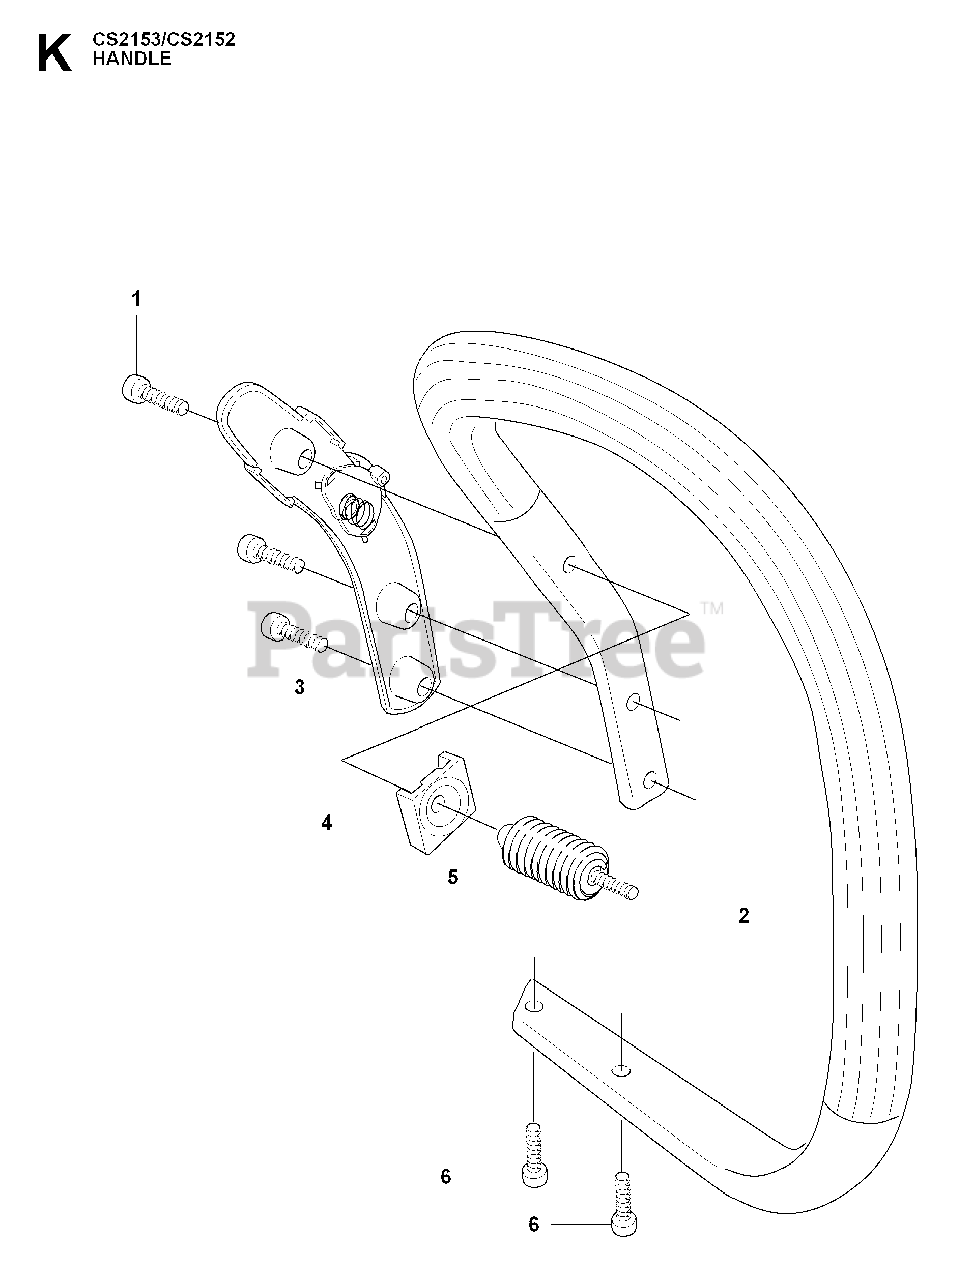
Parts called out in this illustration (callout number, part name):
2	FRONT HANDLE
5	INSULATOR
6	SCREW IHSCFT
